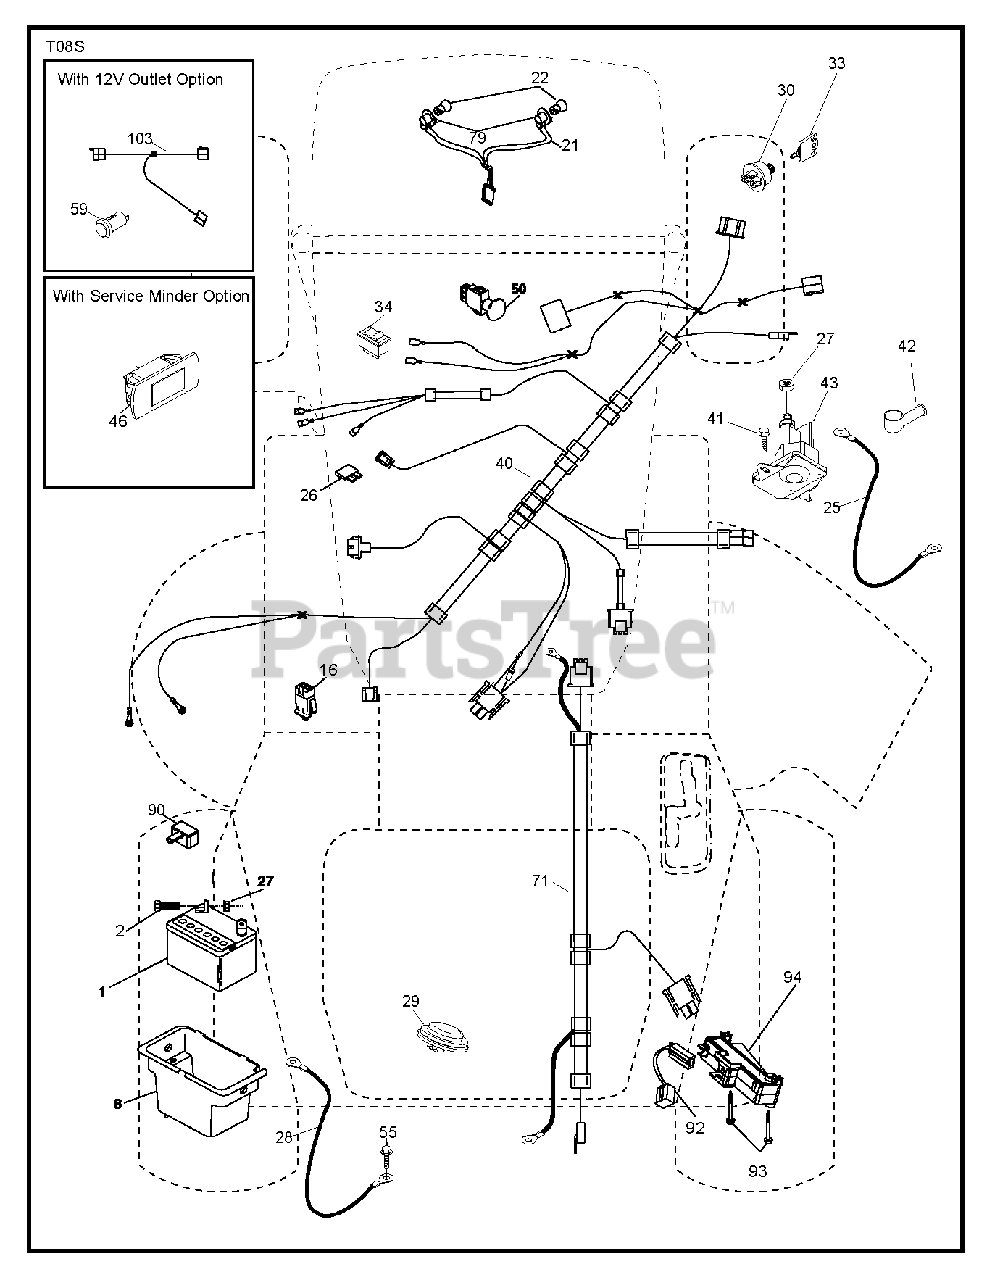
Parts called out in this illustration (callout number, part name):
1	Battery, Dry 30 Amp
2	BOLT.HEX.1/4.X.3/4.DICHROMATE
8	BOX.BATTERY.MNT.REAR.L
16	SWITCH INTERLOOK PUSH-IN
21	HARNESS.LIGHT W/4152J BULBS
25	CABLE.STARTER.6GA.BL/RED.14.
26	FUSE 20AMP
27	NUT
28	CABLE.BLACK.18"REAR.BA
29	SWITCH.SEAT.DELTA.OPC.
30	SWITCH.IGN.DELTA.W.LGH.ROS
33	KEY.CHAIN.BLISTER.PACK.GEN.INT
40	HARNESS.IGN.DASH.HUQ/P
41	SCREW
42	TERMINAL COVER
43	SOLENOID.W/BRASS.PLUNGER
50	RB PTO.SWITCH.8 TERMINAL.BLACK
55	SCREW 5/16"
71	HARNESS.IGN.CHASS.TEX.REAR.BAT
79	BULB HOLDER ASM.
90	COVER.TERMINAL.BATTERY
92	HARNESS.PIGTAIL.CONSLE
93	SCREW.PLASTITE
94	MODULE.REVERSE.ROS
